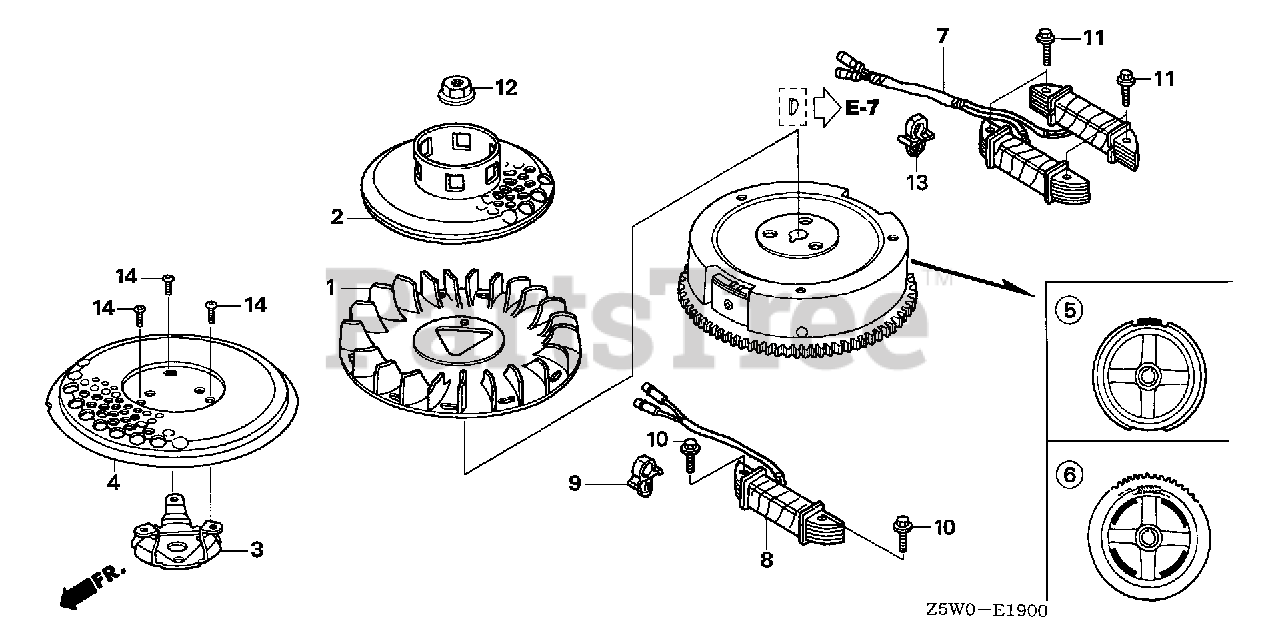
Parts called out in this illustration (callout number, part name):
1	FAN, COOLING
2	PULLEY, STARTER (SCREEN GRID)
6	FLYWHEEL (SEL-4POLE)
8	COIL ASSY., CHARGE (4A)
9	CLIP, BRAKE PIPE (A)
10	BOLT, FLANGE (6X28) (CT200)
12	NUT, SPECIAL (16MM)
